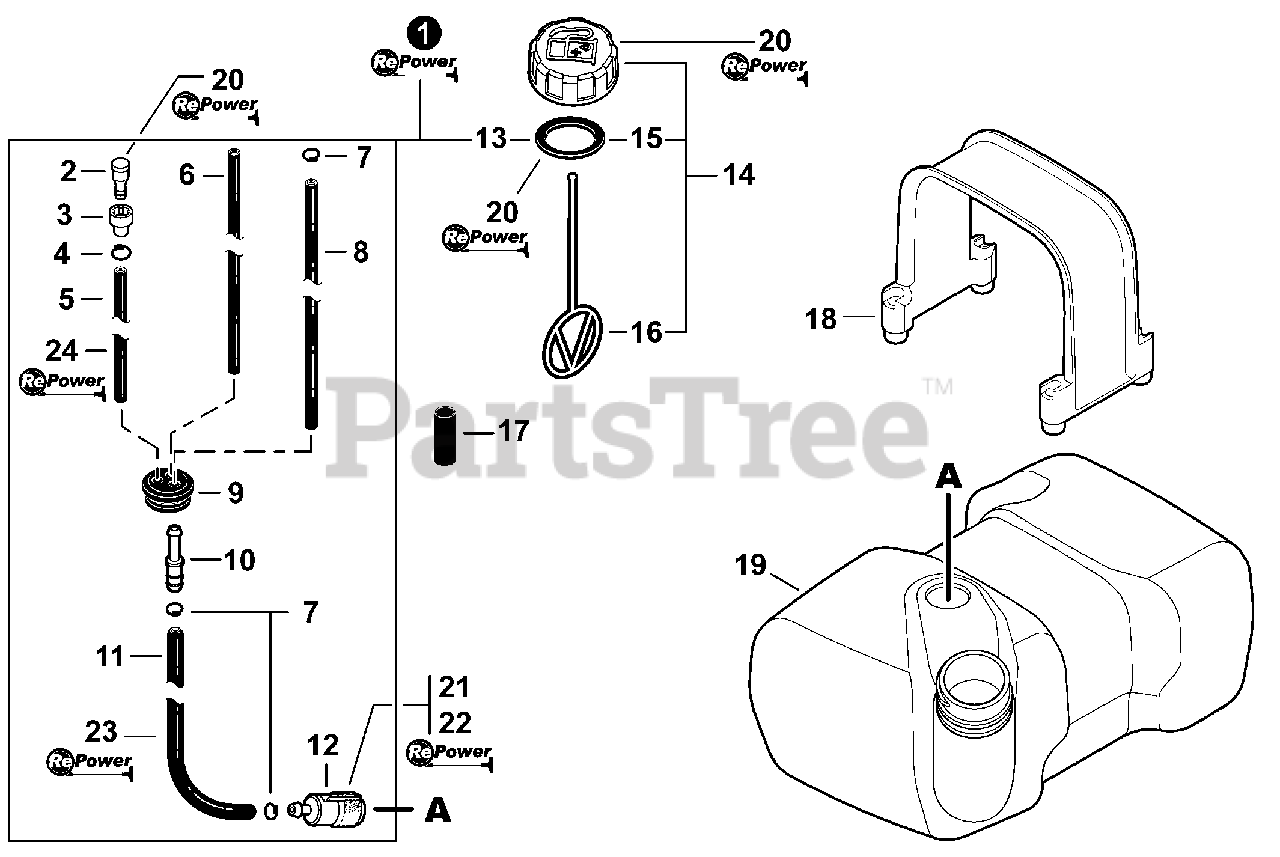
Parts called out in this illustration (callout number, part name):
1	FUEL SYSTEM KIT - REPOWER
2	VENT ASSY
3	HOLDER, VENT
4	CLIP Ø6.5MM
5	PIPE, FUEL VENT 3×6×130
6	PIPE 2.4×5×200 BLACK
7	CLIP Ø6
8	PIPE, FUEL 3×5×135L
9	GROMMET, FUEL
10	CONNECTOR, PIPE Ø5ר3.5
11	PIPE, FUEL 3×5×105L
12	FILTER, FUEL
13	GASKET, FUEL CAP
14	CAP ASSY, FUEL
15	GASKET, FUEL CAP
16	CONNECTOR, CAP L= 100mm
17	TUBE, FUEL LINE 16×18×L40
18	RETAINER, FUEL TANK
19	TANK, FUEL
20	CAP/VENT KIT - REPOWER
21	TUNE-UP KIT - REPOWER
22	FILTER KIT - REPOWER
23	PIPE, BULK - REPOWER 3×5mm BLACK
24	PIPE, BULK - REPOWER 3×6mm BLACK
